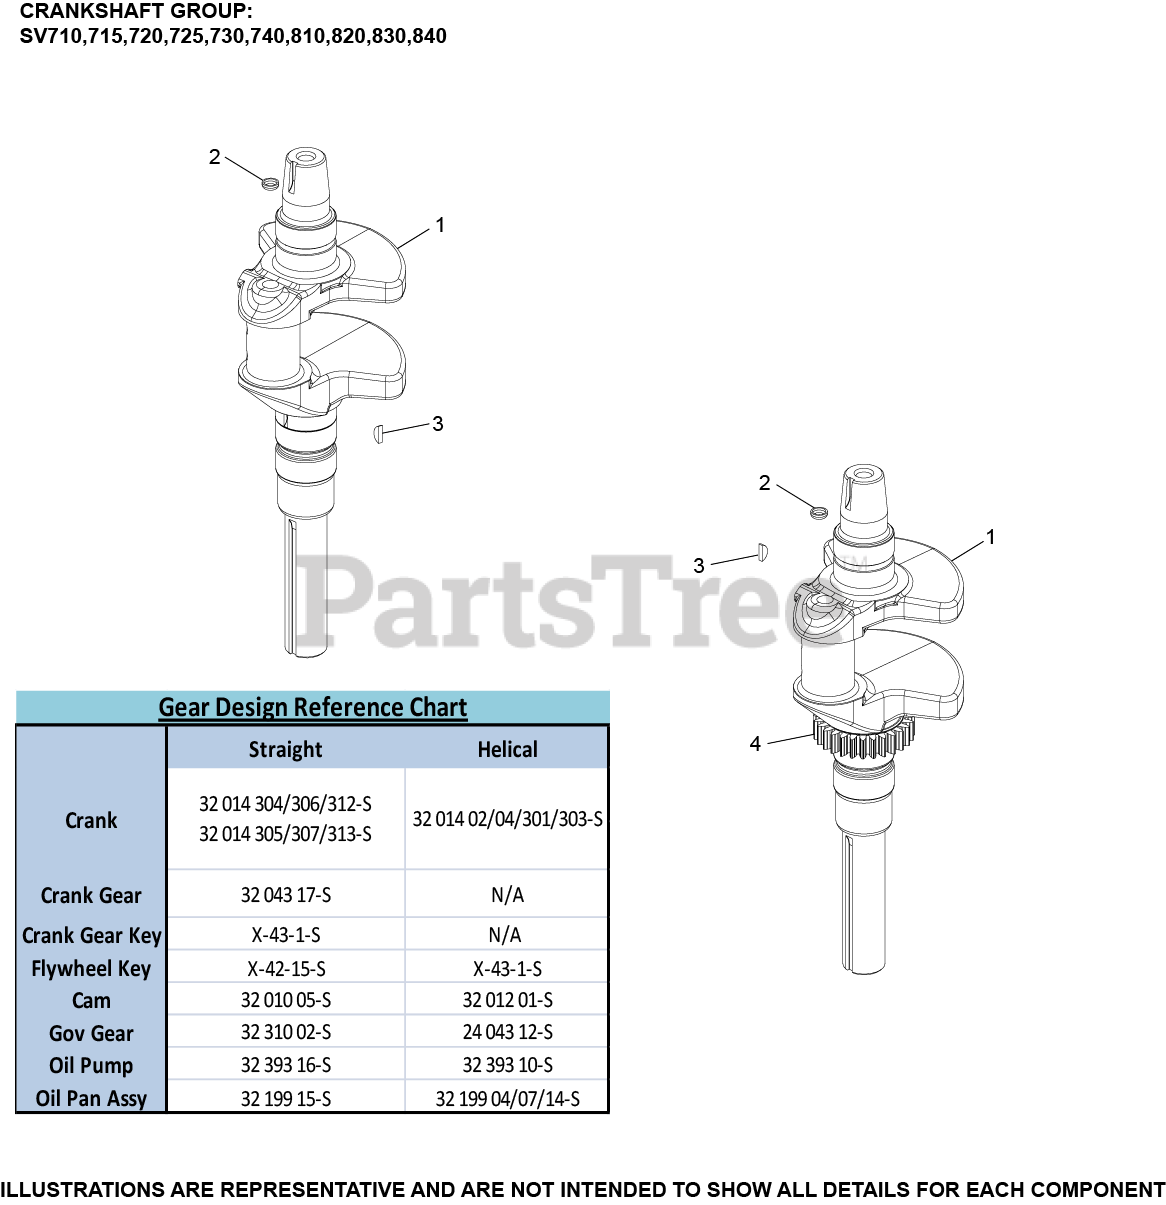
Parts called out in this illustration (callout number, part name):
1	CRANKSHAFT ASSEMBLY USE 32 014 327-S
2	PLUG, CUP
3	KEY, 1/8" X 1/2"
4	GEAR, CRANKSHAFT
